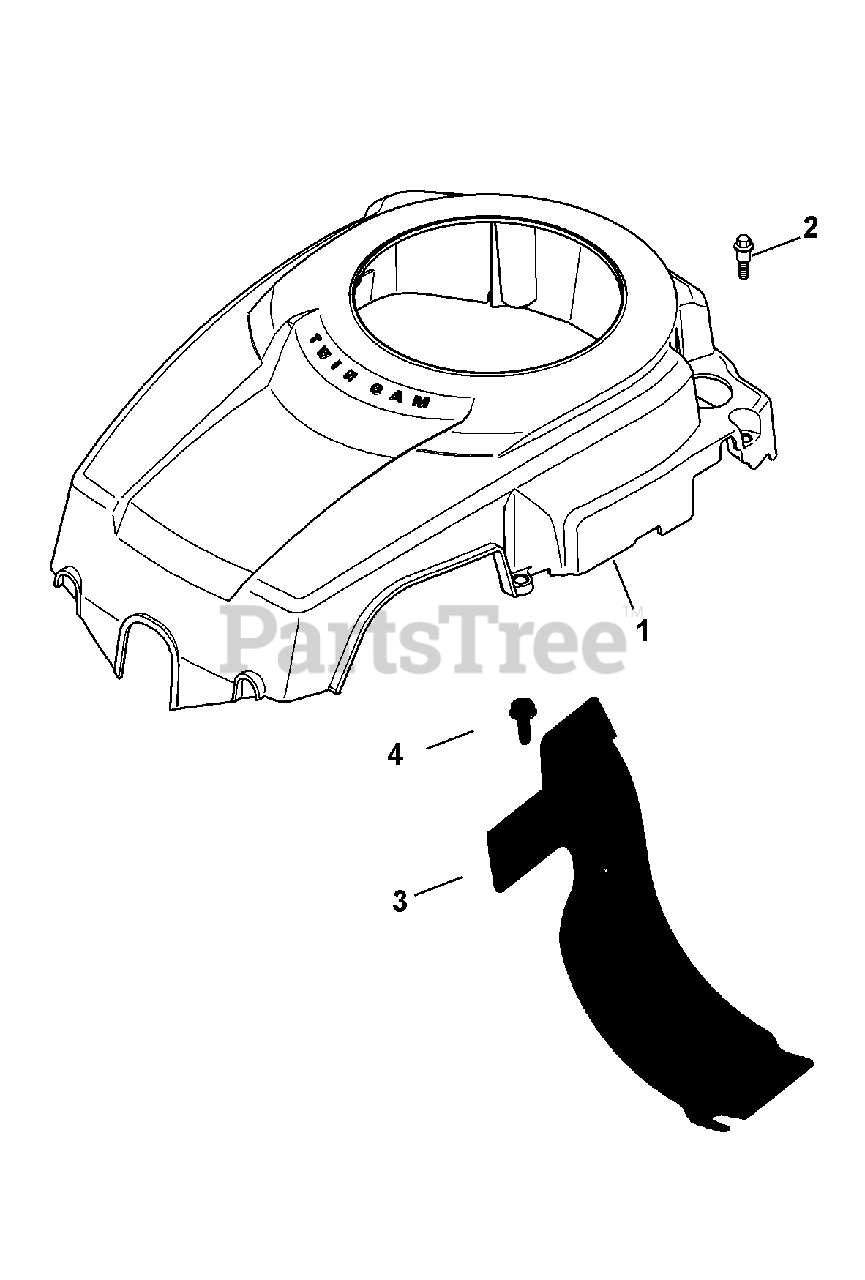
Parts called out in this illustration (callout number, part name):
1	Blower Housing Kit (Inc. 3)
2	Shd. Thd. Frm. Screw, M6 X 1 X 26
3	Baffle Baarrel
4	Screw-Hex Flange M6 x 1.0 x 16
